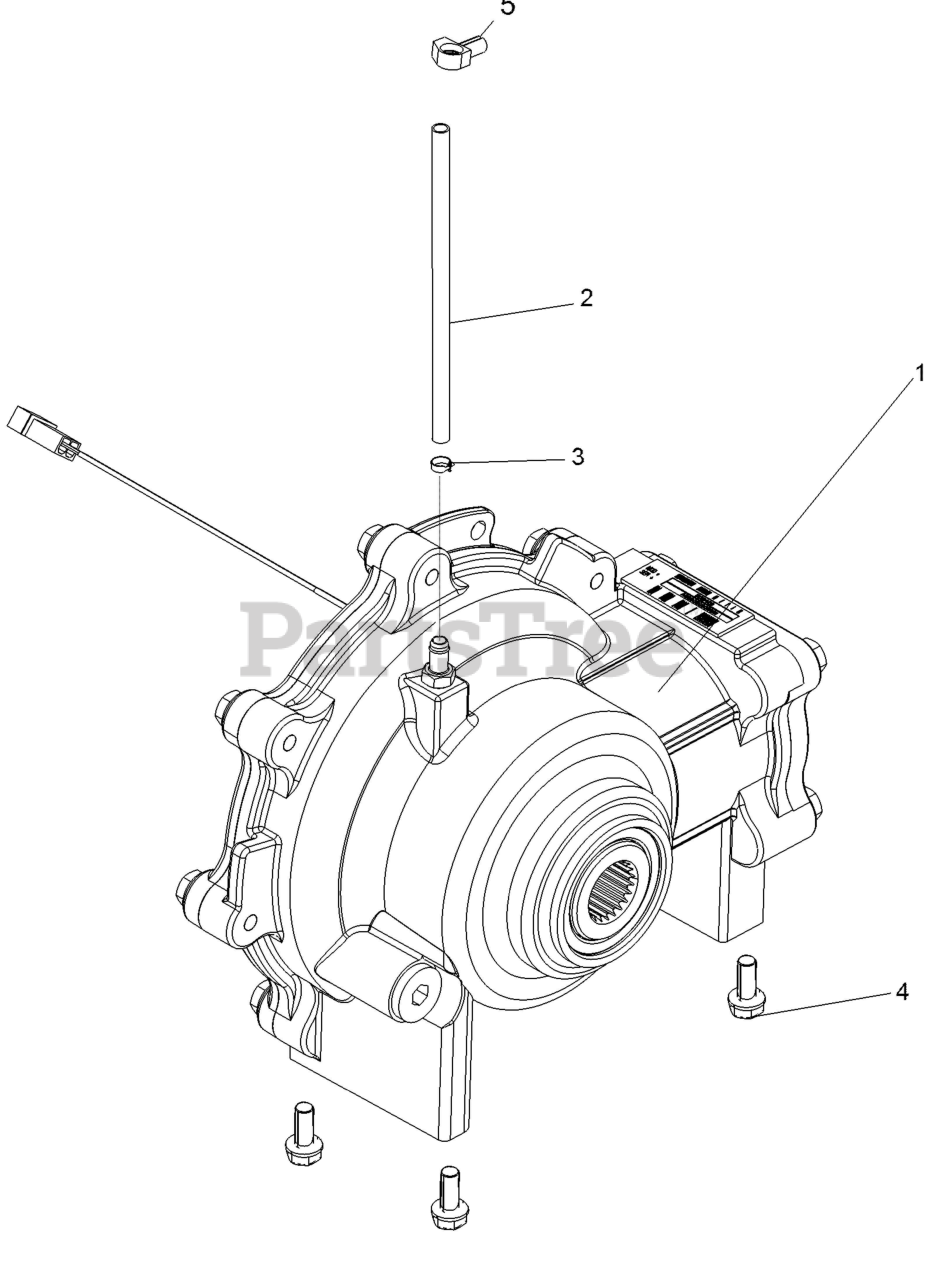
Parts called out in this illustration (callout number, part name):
1	ASM., FRONT GEARCASE 12 POCKET
2	LINE-BOOST,3/16 ID,76CM
3	CLAMP,HOSE(10)
4	BOLT-M10X1.5X20,HXFLG,W/PATCH
5	CLIP,ROUTING,.472 B.D.,HINGED
